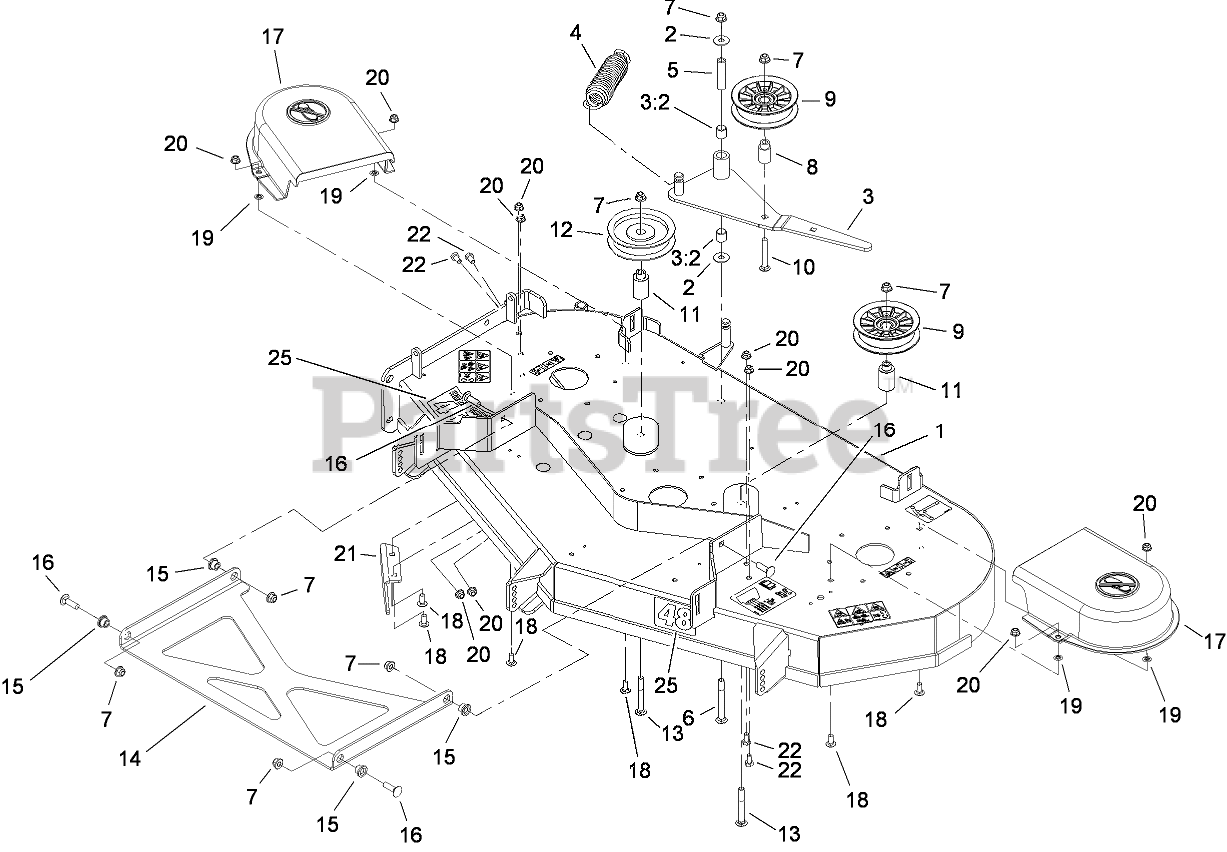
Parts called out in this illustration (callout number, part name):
1	48 INCH DECK ASM
2	WASHER
3	IDLER ARM ASM
3:2	SLEEVE-BEARING
4	Spring-Extension
5	BUSHING-PIVOT, IDLER
6	SCREW-CARR
7	NUT-HF, NI
8	BUSHING-IDLER
9	SHEAVE AND BEARING ASM
10	SCREW-CARR
11	BUSHING-IDLER
12	PULLEY-IDLER
13	BOLT-CARRIAGE
14	STRUT-DECK
15	BUSHING-FLANGED
16	BOLT-CARR
17	SHIELD-BELT
18	SCREW-CARR
19	RING-RETAINING, BOLT
20	NUT-HF, NI
21	BAFFLE-DISCHARGE
22	SCREW-HH
25	DECAL-TITAN, 48 INCH DECK
